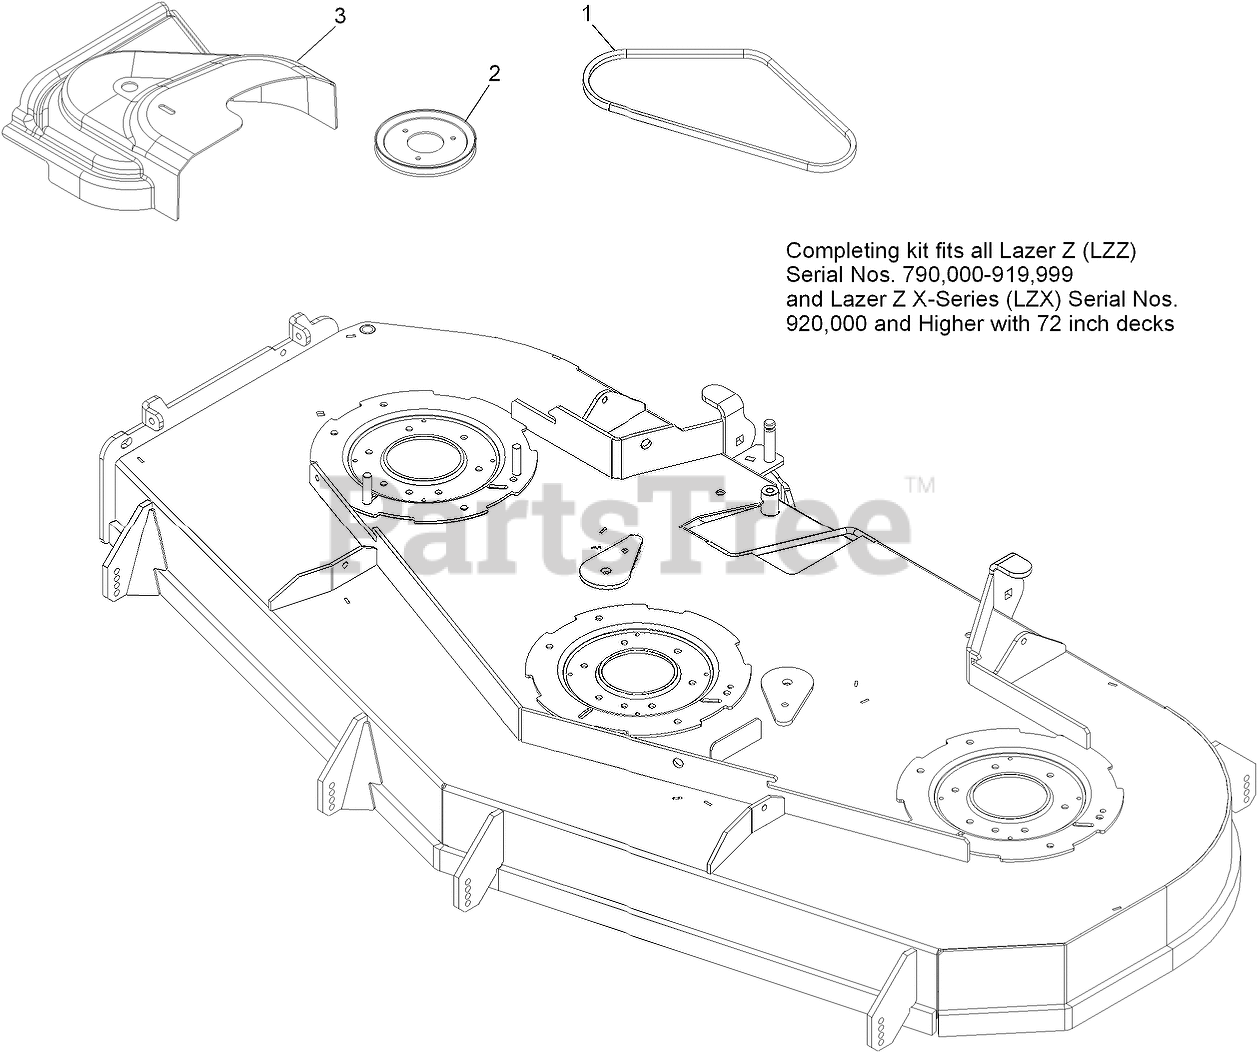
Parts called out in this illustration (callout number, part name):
1	BELT, BLOWER DRIVE 72
2	SHEAVE,DRIVE LZUV 726
3	COVER,BELT UV 72
